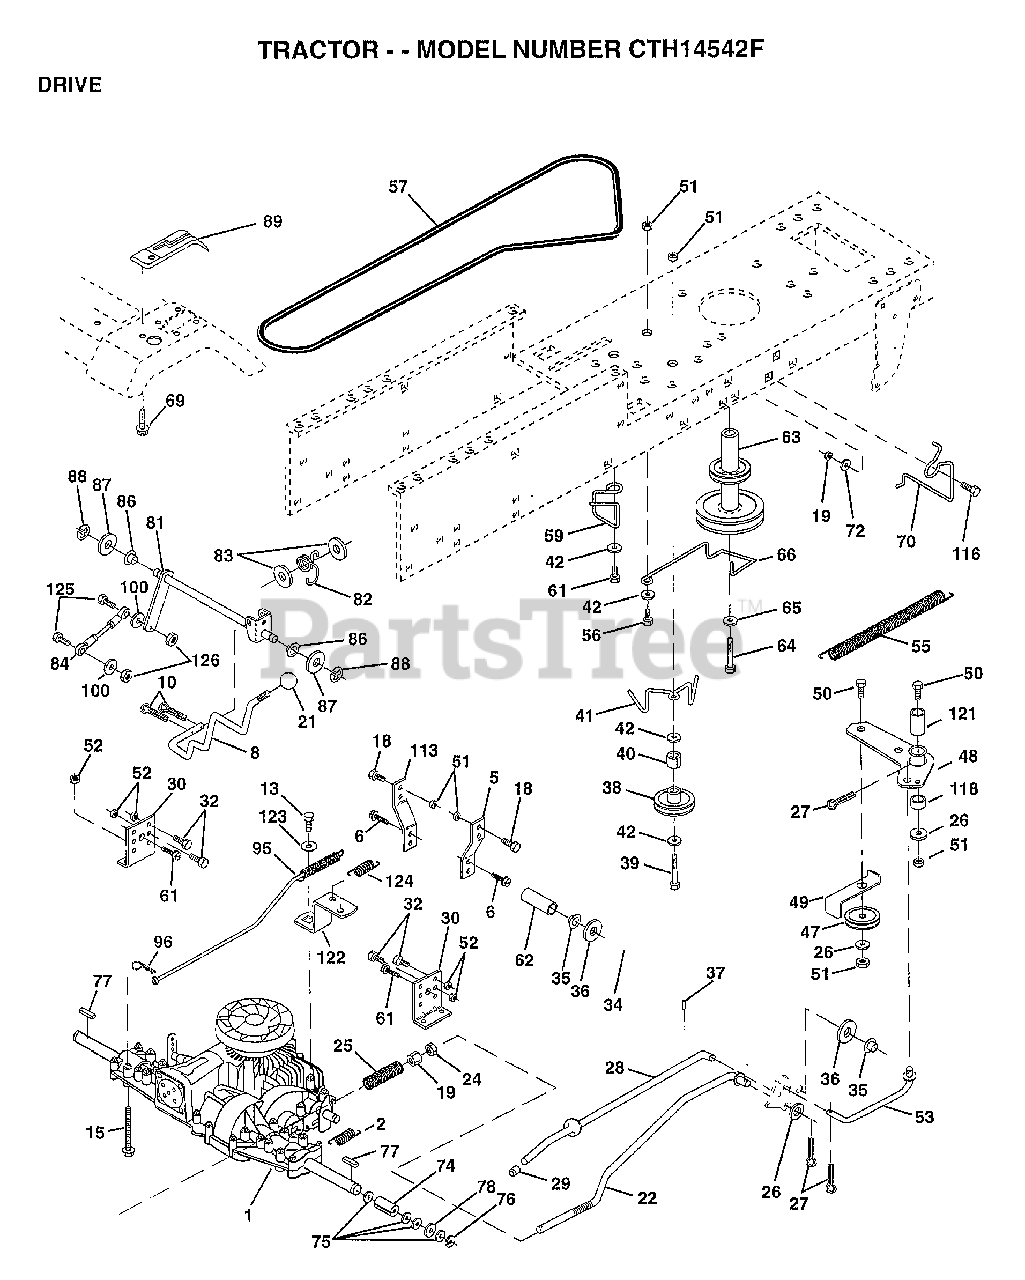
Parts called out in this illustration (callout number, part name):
1	TRANSAXLE, PEERLESS
2	SPRING.BRAKE.RETU
5	STRAP TORQUE
6	SCREW
8	ROD SHIFT FEND LT
10	PIN COTTER 1/8
13	BOLT.1/4-28.W/PAT
15	BOLT.HX.FLG.5/16
18	BOLT
19	NUT
21	KNOB DLX BLK/BLK
22	BRAKE ROD
24	NUT
25	SPRING ROD LT
26	WASHER
27	COTTER PIN
28	ROD.BRAKE.PARK.LT
29	PLUNGER CAP T
30	TRANSAXLE MTG BKT
32	BOLT
34	SHAFT ASM-PEDAL F
35	NYLON BEARING
36	WASHER LT
38	PULLEY.IDLER.FLAT
39	BOLT
40	SPACER T
42	WASHER
48	BELLCRANK ASM
49	RETAIN BELT
53	"LINK, CLUTCH T"
55	"SPRING, RETURN LT"
57	"V-BELT,GRD DRIVE"
59	KEEPER BELT CNTSP
61	SCREW
62	PEDAL COVER T
63	PULLEY.ENGINE
64	BOLT
65	LOCKWASHER
66	KEEPER-BELT
69	SCREW HEXWSH H-L
70	KEEPER BELT ENG
72	WASHER
74	"SPACER AXLE,PVST"
75	WASHER
76	E-RING LT
77	SQUARE KEY
78	WASHER
81	SHAFT ASM CROSS
82	"SPRING,TORSION"
83	WASHER
84	"ROD TIE, PVST 20"""
86	BUSHING
87	WASHER D
88	KLIP RING
95	ROAD ASM BYPASS
96	RETAINER M
100	WASHER M
113	"STRAP,TORQUE"
116	BOLT RDHD 3/8-16
118	SPACER-BELLCRANK
121	NYLINER-CLUTCHING
122	"PLATE-BYPASS,PVST"
123	WASHER
124	SPRING RETURN
